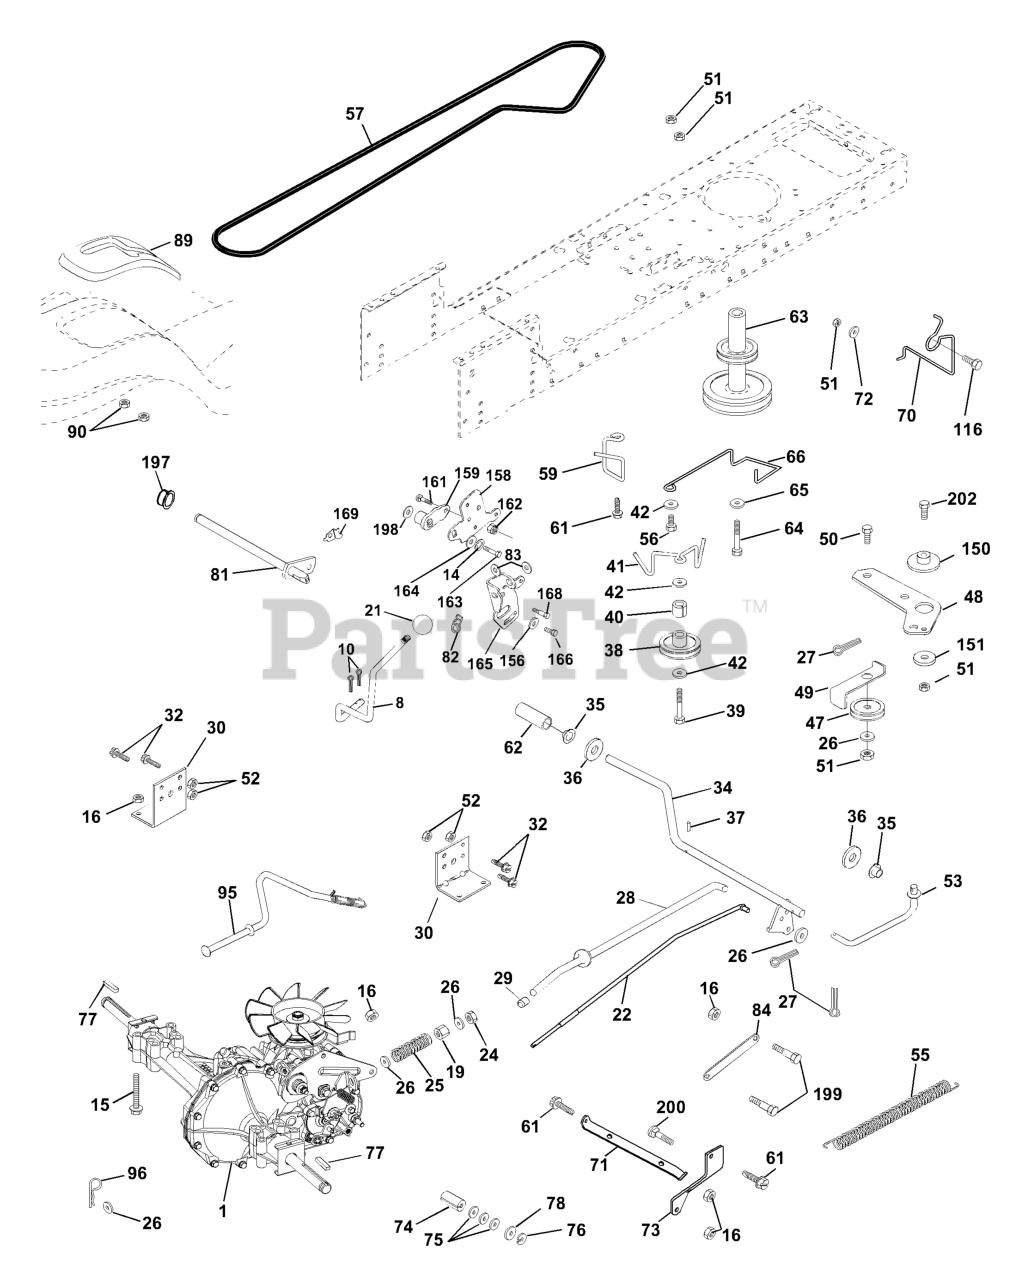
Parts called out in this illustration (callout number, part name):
1	Transaxle Hydro Gr Model 322-0510 (Order parts from transaxle mfg.)
8	ROD SHIFT FENDER ADJUST STLT
10	PIN COTTER
14	LOCKWASHER
16	NUT.71038.31-18.HEX.NYLOCK
19	NUT
21	KNOB.DUCKHEAD.1/2
22	ROD BRAKE HYDRO
24	NUT
25	SPRING ROD LT
26	WASHER
27	COTTER PIN
28	ROD BRAKE PARK LT
29	PLUNGER CAP
30	BRKT, TRNSXLE MNT 20"
32	BOLT
34	SHAFT, FOOT PEDAL
35	BEARING.NYLON
36	WASHER LT
37	DRIVE PIN
38	FLAT IDLER PULLEY
41	KEEPER.BELT.IDLER.FLAT
42	WASHER
47	IDLER PULLEY
48	BELLCRANK, CLUTCH
49	RETAIN BELT
50	BOLT.3/8-16X1.50
52	LOCKNUT
53	LINK, CLUTCH LT
55	SPRING, RETURN LT
57	DRIVE BELT, LTH & YTH TRACTORS
59	Keeper, Center Span
61	SCREW 3/8-16X3/4
62	PEDAL COVER T
63	PULLEY.ENG.CL.MECH.SLVR.LT/YT
64	BOLT
65	LOCKWASHER
66	KEEPER BELT ENGINE
70	KEEPER BELT ENG
71	STRAP TORQUE LH HYDRO
72	WASHER
73	STRAP TORQUE RH HYDRO
74	SPACER AXLE
77	SQUARE KEY
81	SHAFT ASM CROSS TAPERED
82	SHIFT SPRING
83	WASHER
84	LINK TRANSAXLE
89	SHIFT CONSOLE
90	NUT.PUSH.3/16
93	LINE FUEL HYD 4"
95	CONTROL ASM. BYPASS HYDRO
96	RETAINER M
115	BOLT HEX 5/16-18 GR 5
116	BOLT
150	BUSHING.BELLCRANK.GRD.DR
151	WASHER 12/32X2X10GA
156	WASHER.SRRTD.5/16
158	BRACKET
159	HUB
161	BOLT
162	NUT.CROWNLOCK.1/4
163	BOLT
164	Washer 5/8 x .281 x 10 Ga
165	RP BRACKET
168	BOLT.SHOULDER.5/16-18X
169	PLATE.FASTENING.CROSS.SHAFT
197	NYLINER SNAP 5/8" ID
198	WASHER.NYL.7/8IDX.105"HYD CR
199	BOLT SHOULDER 5/16-18 UNC
200	Bolt Rdhd Sq Neck Unc
201	SCREW
